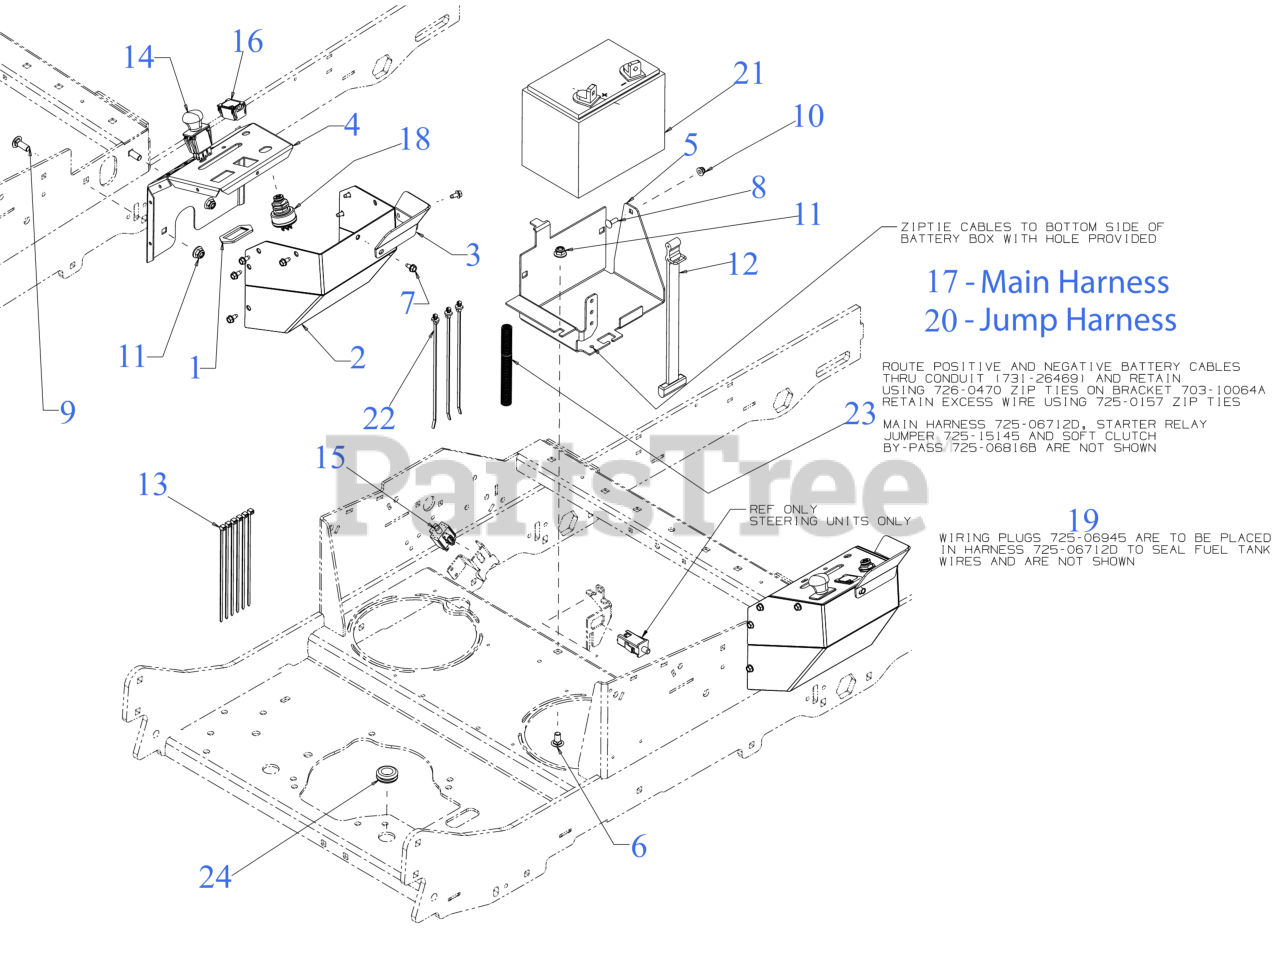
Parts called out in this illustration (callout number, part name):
1	BRACKET-PTO SWITCH
4	CONTROL POD (RH)
5	BATTERY MOUNT BRACKET
6	CARRIAGE BOLT 3/8-16 x .750 GR5
7	SCREW 1/4-20 X.500
8	SCREW 1/4-20 x .75 GR5
9	CARRIAGE BOLT 3/8-16 x 1.00 GR5
10	FLANGE LOCK NUT
12	BATTERY RETAINER STRAP
13	7" CABLE TIE
14	PTO SWITCH (BLACK KNOB) TEXT SYM
15	3 POLE SWITCH ( NC-NO-NO)
17	WIRE HARNESS ASSEMBLY (KOH/KAW EFI)
18	KEY SWITCH (3 POSITION)
18	PRO-Z KEY SET
19	SEALED CAP ASSEMBLY
20	JUMPER HARNESS (W/RELAY)
21	BATTERY (230 CCA AGM U1-280)
22	CABLE TIE
23	CONVOLUTED CONDUIT 1"
24	RUBBER GROMMET
